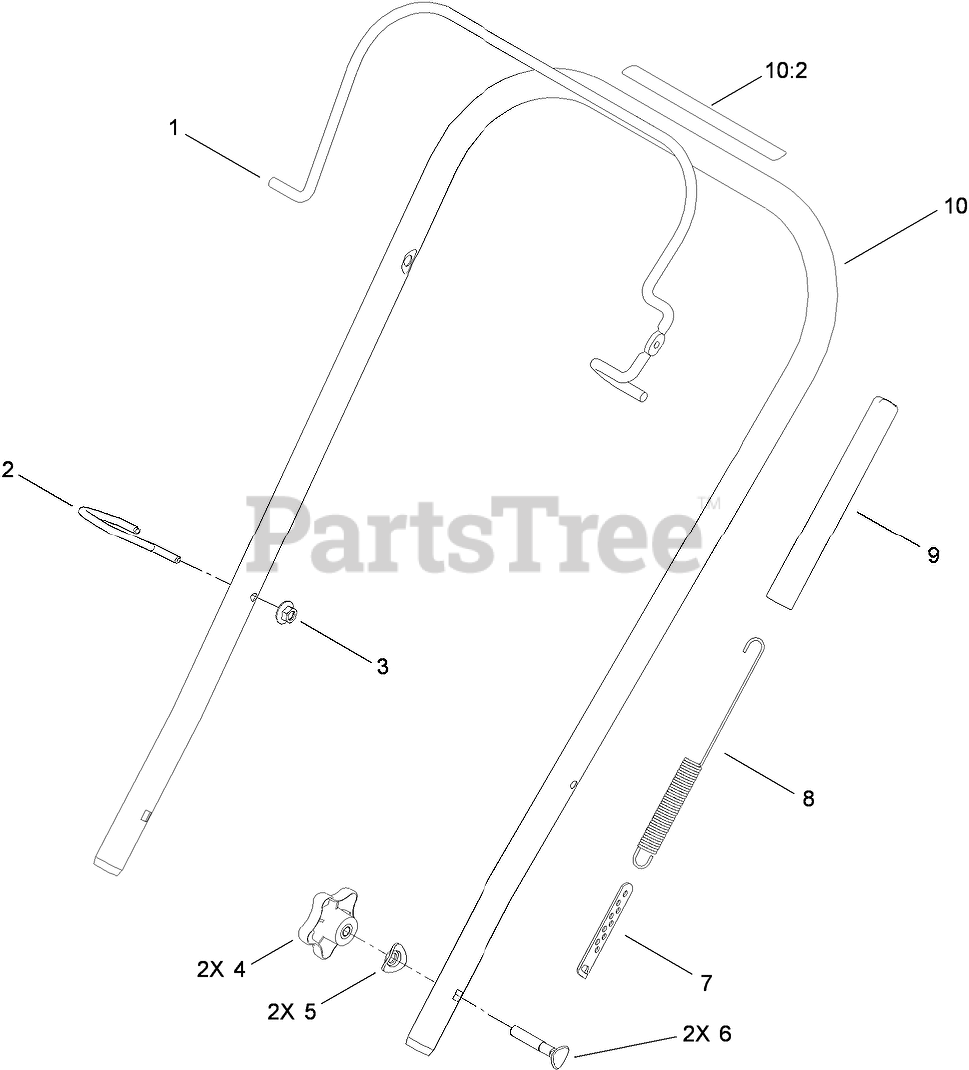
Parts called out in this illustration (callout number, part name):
1	BAIL-CLUTCH
2	GUIDE-ROPE, RECOIL
3	NUT-HEX FLG
4	KNOB-HANDLE
5	WASHER
6	SCREW-HANDLE
7	ADJUSTER-CABLE, CLUTCH
8	SPRING-CLUTCH
9	COVER-SPRING
10	UPPER HANDLE ASM
10:2	DECAL-SAFETY
